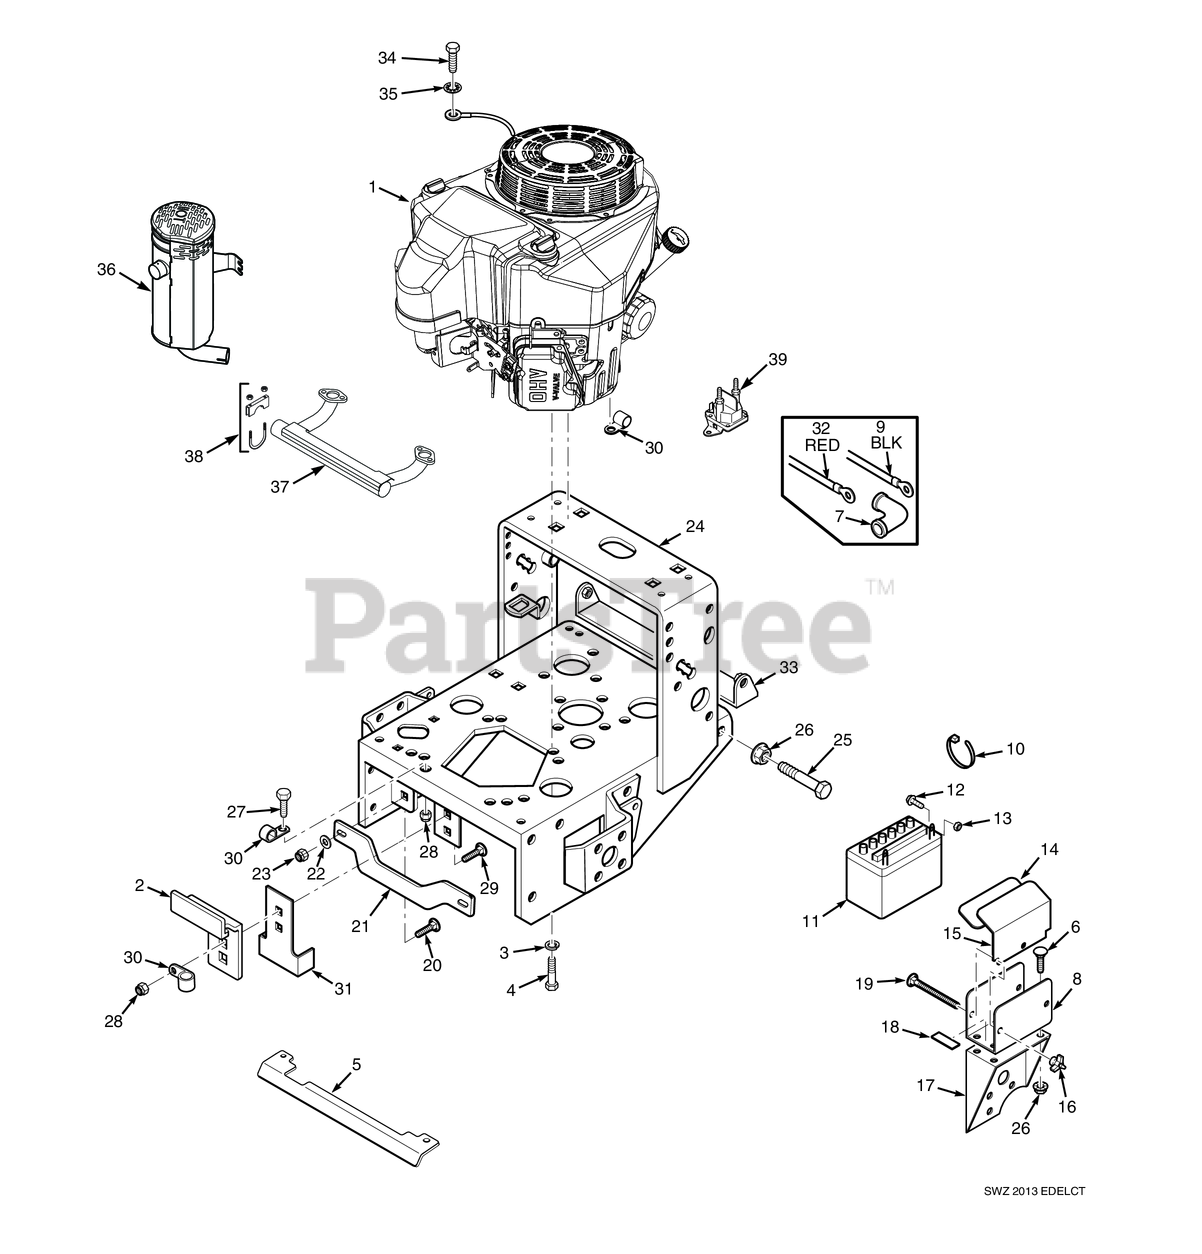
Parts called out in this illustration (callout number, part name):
2	Plate, Clutch Bracket
3	Lockwasher, 3/8" Spring, Kawasaki FX / FS
4	Bolt, Hex Head 3/8-16 x 1-1/4", Kawasaki FX / FS
5	Heatshield, 16" Small Frame
5	Heatshield, 20" Large Frame
6	Bolt, 5/16-18 x .75 RHSN Carriage
7	RUBBER BOOT
8	Plate, Battery Box
9	Battery Cable, 31-1/2" Black (25KA, 26DFI, 31DFI) - Kawasaki
10	Cable Tie, .19 x 8.0"
11	Battery (Not Available Through Scag)
12	Bolt, Hex Head 1/4-20 x .5" Battery, (Not Available Through Scag)
13	Nut, 1/4 - 20 Hex
14	INSULATION, BATTERY COVER
15	Battery Box Cover
16	ELASTIC STOP WINGNUT, 1/4-20
17	Battery Support
18	PAD, BATTERY SUPPORT
19	Bolt, Carriage 1/4-20 x 6"
20	SHORT SQ. NECK CARRIAGE BOLT, 3/8-16 X 1-1/4"
21	Brace, (16" Small Frame)
21	Brace, (20" Large Frame)
22	Flatwasher, 3/8 (.391 x .938 x .105 HD) Grade 8
23	HEX NUT, ELASTIC STOP LOCK, 3/8-16
24	Engine Deck (16" Wide) with Decals - Small Frame
24	Engine Deck (20" Wide) with Decals - Large Frame
25	Bolt, Hex Head 5/16-18 x 2-1/2" (x3) (35BV & 37BV-EFI)
26	Nut, Serrated Flange 5/16-18 (Right Front Engine Mounting, Briggs and Kohler Only)
27	BOLT, SERRATED FLANGE HEX HEAD 5/16-18 X 3/4"
28	HEX NUT, ELASTIC STOP LOCK, 5/16-18
29	Bolt, Carriage 5/16-18x1" (large frame units only)
30	Clamp, Cable 1/2" I.D.
31	Plate, Clutch Anti-Rotation
32	Battery Cable, 25" Red (Kawasaki)
32	Battery Cable, 18.0" Red
33	Pulley Guard, 16" Small Frame
33	Pulley Guard, 20" Large Frame
34	Bolt, Hex Head M8 - 1.25 x 16 (48V / 52V)
35	Lockwasher, 5/16" Ext. Tooth (Kohler x1)
36	Muffler, Kawasaki (FS481, FS541, FS600)
36	Muffler, Kawasaki (FS651) - SWZT61
37	MANIFOLD, 18 FS ENGINE
37	Manifold, Kawasaki (FS651) - SWZT61
38	Muffler Clamp
38	Clamp, Muffler 1.25 Dia. Kawasaki
39	Solenoid, Sealed (Briggs & Stratton)
